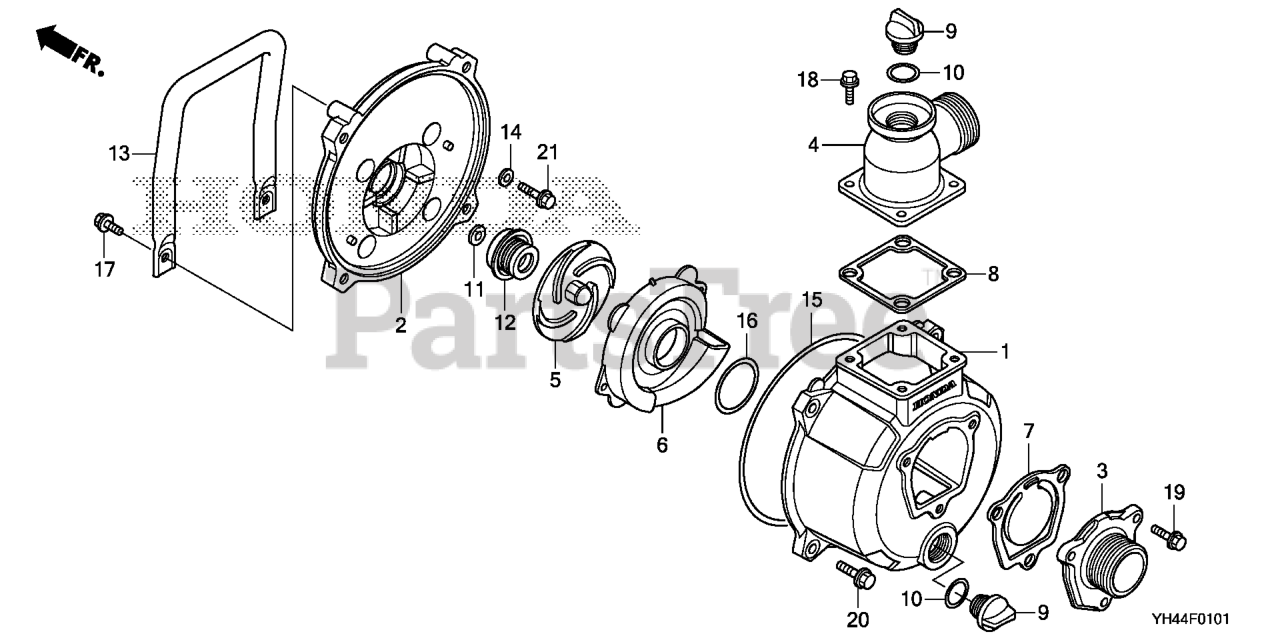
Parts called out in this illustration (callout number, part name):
2	COVER, CASING
3	INLET (NPT1 1/2)
4	OUTLET (NPT1 1/2)
6	CASE, VOLUTE
7	VALVE, IN.
8	GASKET, OUTLET
9	CAP, FILLER
10	O-RING (23.7X3.5)
11	SHIM, ADJUSTER
12	SEAL ASSY., MECHANICAL
14	WASHER, SEALING (6MM)
15	O-RING (174X3.5)
16	O-RING (41.5X5.7)
17	BOLT, FLANGE (6X14)
18	BOLT, FLANGE (6X20)
19	BOLT, FLANGE (6X25)
20	BOLT, FLANGE (8X28)
21	BOLT, FLANGE (6X28)
